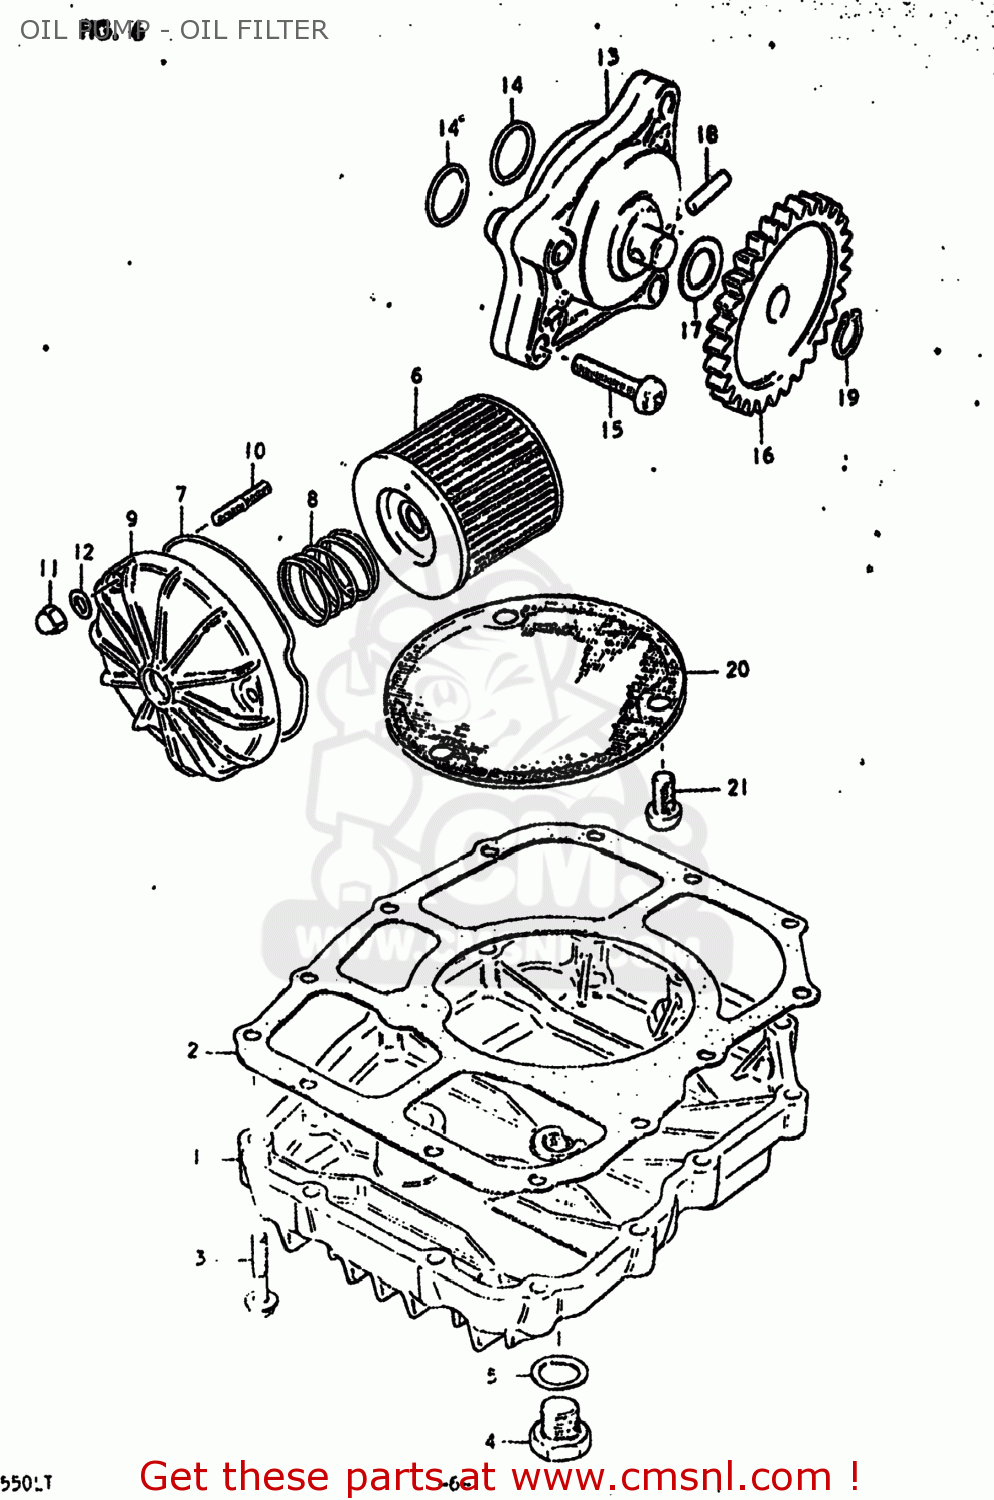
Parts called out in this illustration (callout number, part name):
1	PAN,OIL
2	GASKET,OIL PAN (MCA)
3	BOLT
4	PLUG
5	GASKET(14X19.2X2) (NAS)
6	FILTER ASSY,ENGINE OIL
7	O RING,OIL FILTER CHAMBER CAP
8	SPRING
9	CAP,OIL FILTER
10	STUD 6X20
11	NUT
12	WASHER
13	PUMP ASSEMBLY,OIL
14	O RING(D:1.9,ID:13)
15	SCREW
16	GEAR,OIL PUMP DRIVEN
17	SHIM
18	PIN(4X15.8)
19	CIRCLIP
20	STRAINER,ENGINE OIL
21	SCREW 6X12
